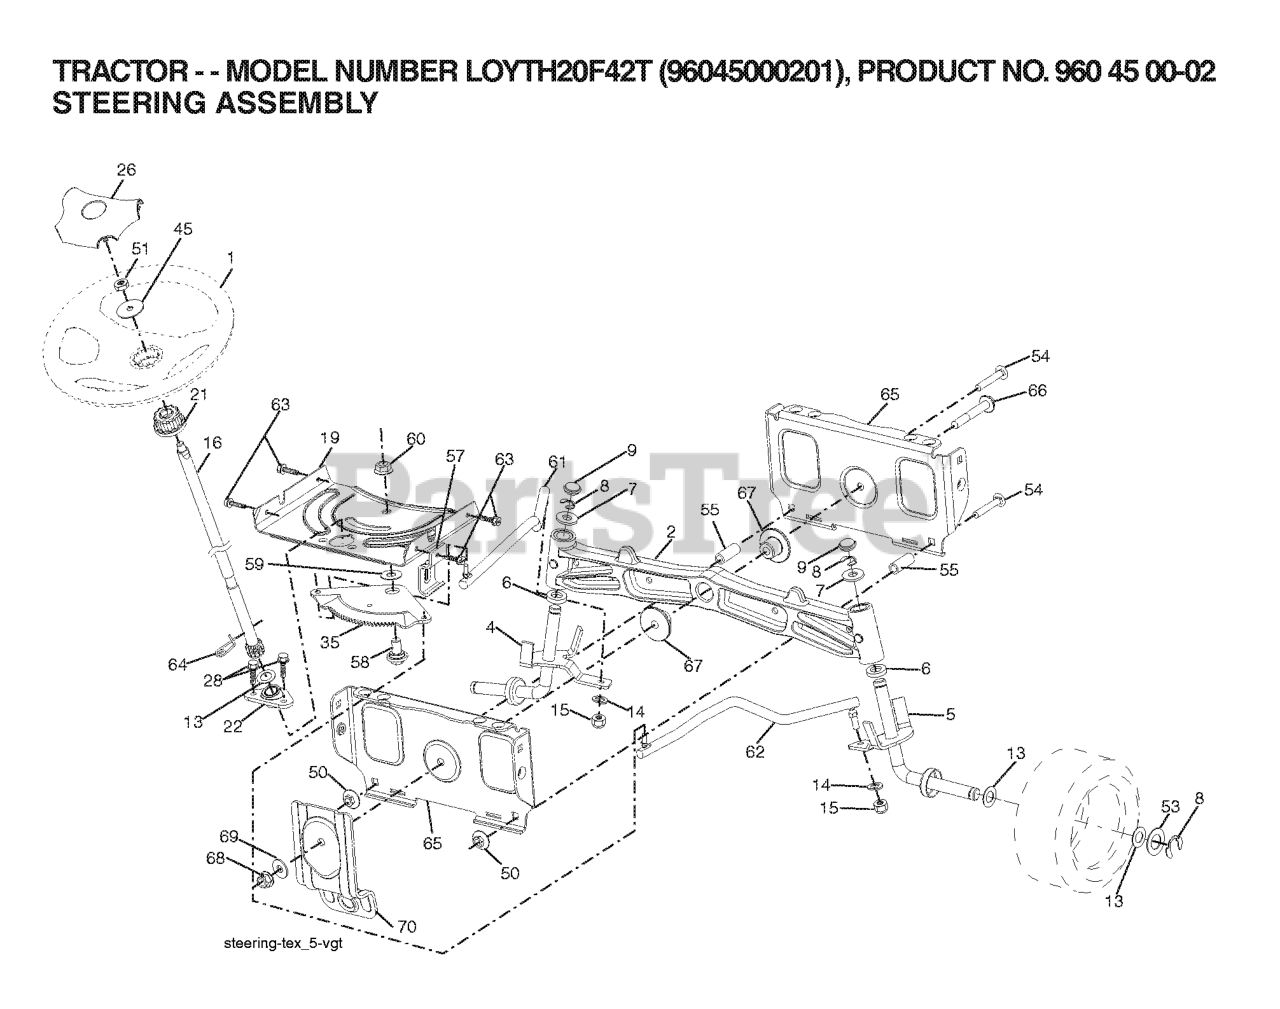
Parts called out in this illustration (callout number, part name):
1	WHEEL.STEERING.LEGEND2.GRY
2	AXLE.CAST.IRON
4	SPINDLE.WELDED.LH.15"TEX
5	SPINDLE.WELDED.RH.15"T
6	THRUST WASHER
9	CAP.SPINDLE.BLACK
14	WASHER, LOCK 3/8
15	NUT CROWNLOCK 3/8-24
16	SHAFT.STEER.STEALTH.DD
19	PLATE.STEER.DDL.NLT/NG
21	ADAPTER, WHEEL STNG..
22	BUSHING.ASM.STEERING.A
26	INSERT.CAP.STRG.WH.GRAY
28	SCREW, 3/8-16X3/4
35	GEAR.SECTOR.PLATE.DDL.
45	WASHER 9/16"ID, 2 3/8"OD
50	NUT LOCK FLG 3/8-16 UNC
51	NUT.HEX.1/2-20
53	WASHER.HARDENED
55	SPACER.BRACE.AXLE (2 2)
57	BRKT.UPSTOP.GT/LT.TEX
58	BOLT.SHOULDER.SECTOR.P
59	WASHER.THURST.SECTOR.S
60	NUT FLANGE LOCK 5/8-11
61	DRAGLINK.LH.BALLSTUD.D
62	DRAGLINK.RH.BALLSTUD.D
63	SCREW
64	RETAINER.CLIP.SPRING.S
65	BRACE.AXLE.FRONT.NLT/N
66	BOLT HEX FGHD 7/16-14 X 3 SERR
67	BUSHING.PM.FRONT AXLE
68	NUT.LOCK.FLANGE.7/16
69	WASHER.1.5X.505X.118
70	BRKT.DECK.SUSPENSION.F
